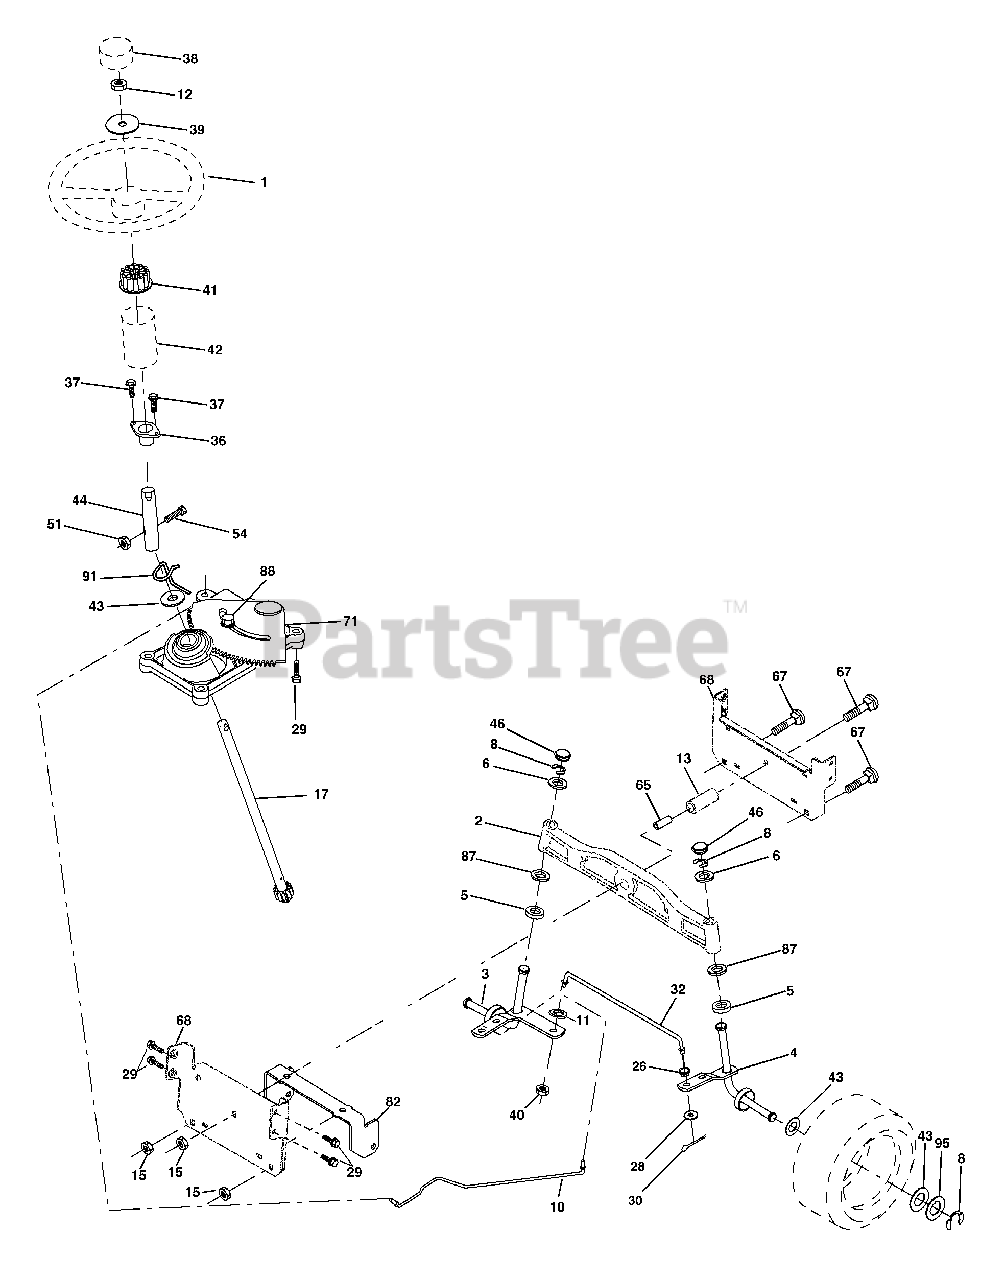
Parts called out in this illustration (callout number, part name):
1	Wheel Steering Auto Black
2	Axle Asm Front
3	Spindle Asm Lh
4	Spindle Asm Rh
5	Bearing Race Thrust Harden
6	Washer 25/32 x 1 5/8 x 16 Ga.
8	Ring Klip #t5304-75
10	Link Drag Extended
11	Lockwasher
12	Nut Hex Jam Toplock 1/2-20 unf
13	Spacer Bearing Axle Front
15	Hex Flange Lock
17	Shaft Asm Strg
26	Bushing Rod Tie Blk Lt
28	Washer 13/32 x 7/8 x 16 Ga.
29	Screw 3/8-16 x 3/4
30	Pin
32	Rod Tie Wire Form 19 75 Mech
36	Bushing Strg 5/8 Id Dash
37	Screw TT #10-32 x 5 x 3/8 Flange
38	Insert Cap Strg
39	Washer 9/16 ID x 2-3/8 OD 12 Gr.
40	Nut Crownlock
41	Adaptor Wheel Strg
42	Boot Dash Steering
43	Washer 25/32 x 1 1/4 x 16 Ga.
44	Extension Steering
46	Cap Spindle Fr Top Blk
51	Nut Crownlock 1/4-28
54	Bolt Hex 1/4-28 unf x 1-1/4 Gr. 8
65	Spacer Brace Axle
67	Bolt Rdhd Sq 3/8-16 unc x 2-1/4
68	Brace Axle
71	Steering Asm
82	Bracket Susp Chassis Front
87	Washer Flat .781 x 1-1/2 x .14
88	Bolt Shoulder 7/16-20
91	Clip Steering
95	Washer Hardened
